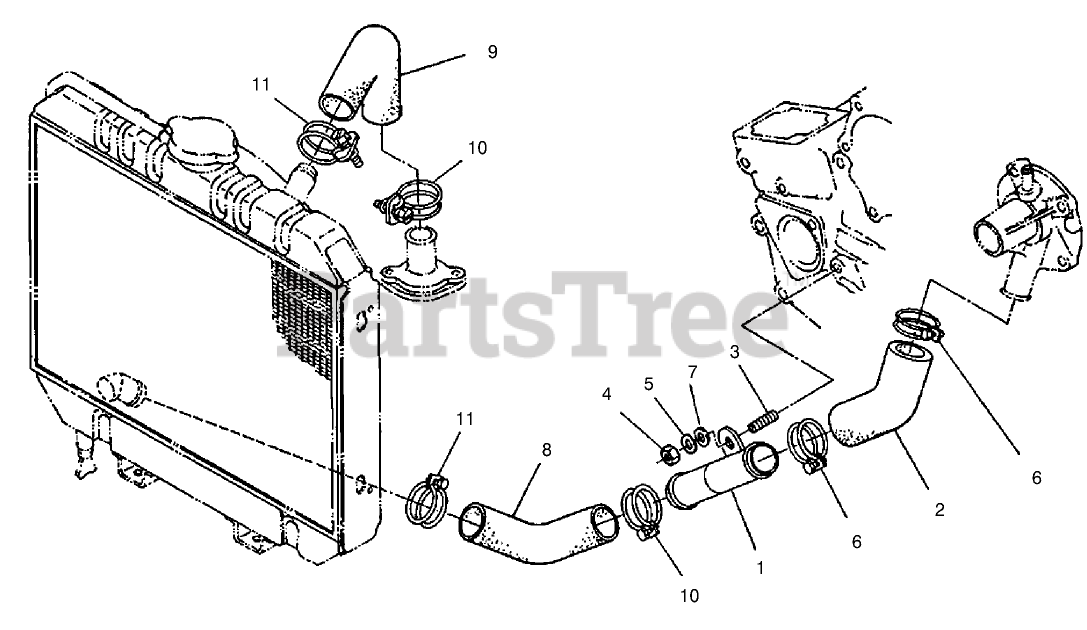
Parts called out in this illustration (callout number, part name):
1	PIPE-WATER
2	PIPE-WATER
5	WASHER-SPRING
6	CLAMP-HOSE
7	WASHER-PLAIN
8	PIPE, WATER
9	PIPE, WATER
10	CLAMP-HOSE
11	CLAMP, HOSE
